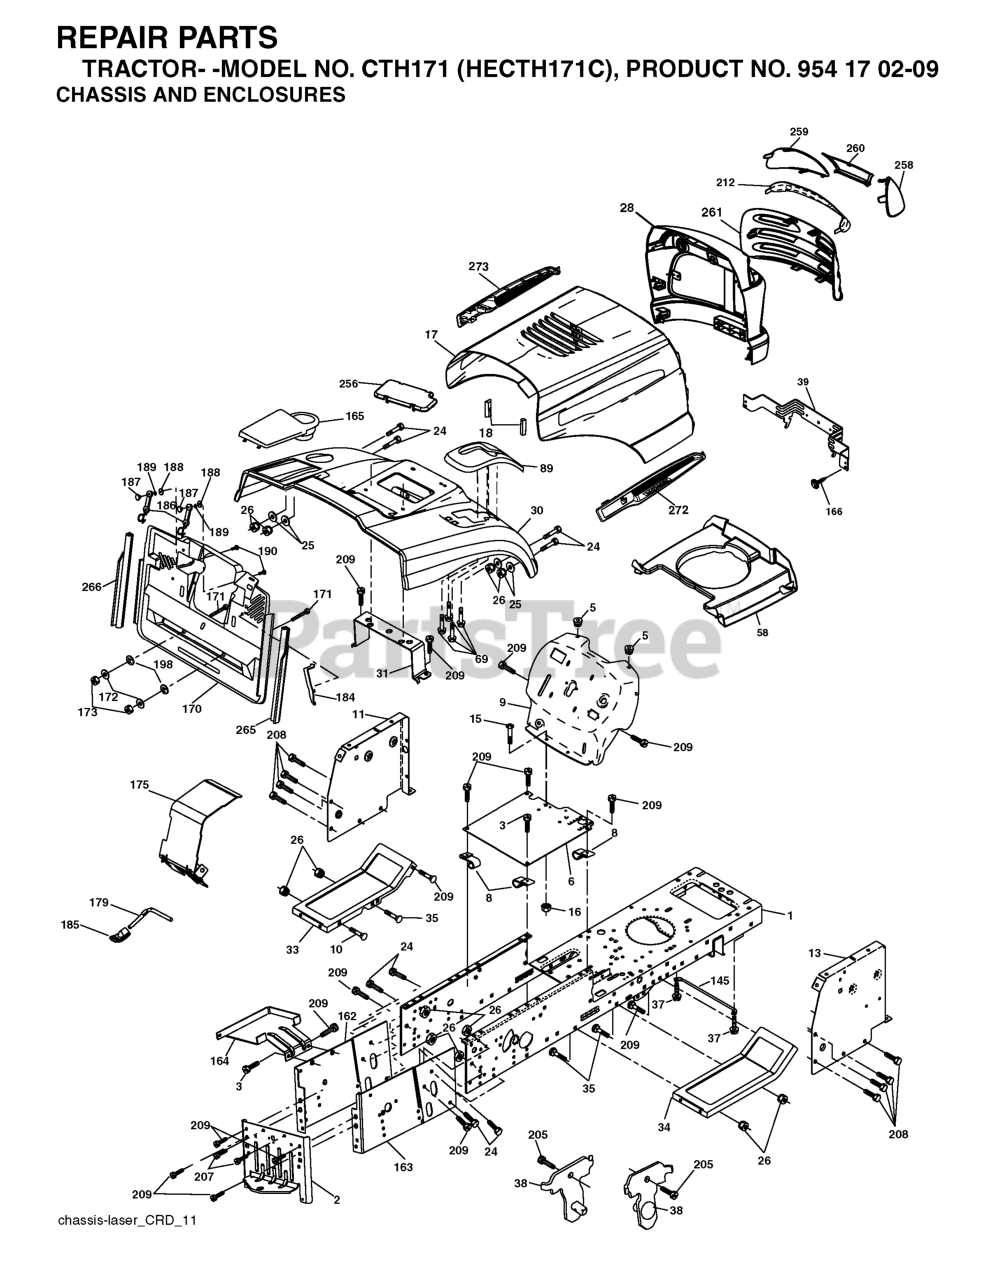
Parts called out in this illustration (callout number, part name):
2	DRAWBAR
3	SCREW 3/8-16X3/4
5	BUMPER.RUBBER.HOOD
6	PLATE
8	CLIP,INSULATOR
10	BOLT D
11	PANEL.DASH.LH.LTX
13	PANEL ASM, DASH RH
15	Screw, Machine, Truss Head 5/16-18 UNC x 3/4
16	NUT
17	VENT.HOOD.LASER.III
18	BUMPER.HOOD.LARGE.1.75"
25	WASHER
26	NUT
31	BRACKET SUPPORT FENDER
33	FOOTREST PNT LH
34	FOOTREST PNT RH
37	Screw 5/16-18 x 1/2 Hex, Self Tapping 5/16-18 x 1/2
38	BRACKET ASM PIVOT MOWER REAR
39	BRACKET PIVOT LASER
69	SCREW.HI-LO.CONSOLE
89	COVER.BATTERY.CRD.GREY
145	ROD PIVOT CHASSIS/HOOD
162	BRACKET
163	BRACKET EXTEN CHASSIS RH CRD
165	RP.COVER.BATTERY.CRD.GREY
166	SCREW
172	WASHER
175	DOOR TRAP
179	ROD PIVOT FBI
184	BRACKET.ACTUATOR.BAGGER.SRD
186	LATCH ASSY
187	WELDNUT
189	LOCKWASHER #10
190	SCREW
207	SCREW, 5/16-18 X 1/2
208	SCREW 3/8-16X1/2
209	SCREW, 3/8-16X3/4
256	COVER FENDER CRD
258	LENS LH
259	LENS LH
260	COVER.LENS.HUSQ.LASER
265	SEALING
266	SEALING
272	VENT.HOOD.LASER.
273	VENT.HOOD.LASER.
